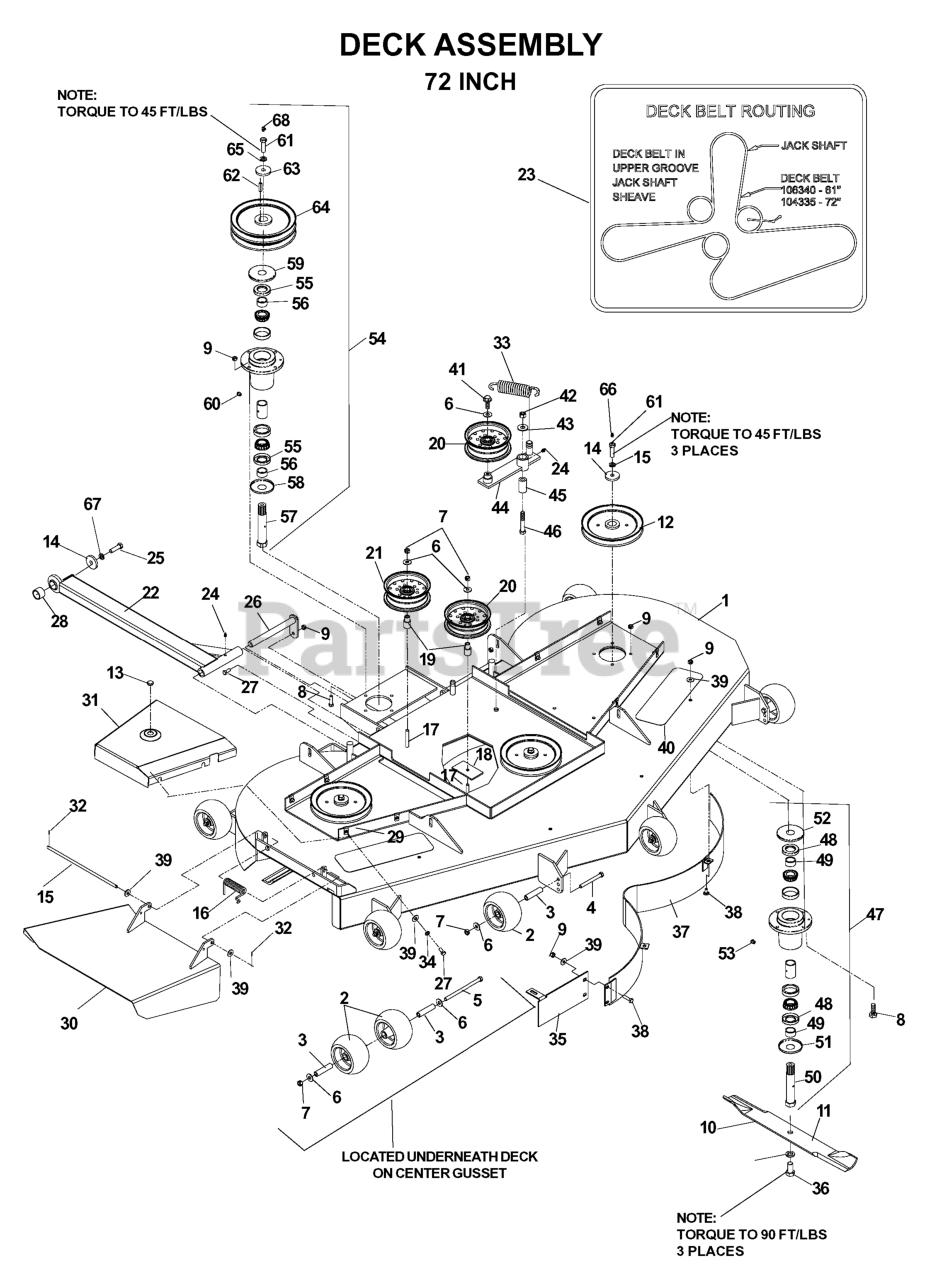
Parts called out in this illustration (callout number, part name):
1	DECK W/DECALS 72" HUS
2	ANTI-SCALP ROLLER
4	HCS 3/8C X 3 1/2
5	BOLT 3/8 X 6" GRD 8
6	WASHER 3/8 FLAT
7	NUT 3/8C CENTERBLOCK
8	HCS 5/16C X 1
9	NUT 5/16C CENTERLOCK
10	BLADE OEM - 25"
11	BELLEVILLE SPRING WASHER
12	RP PULLEY - 72"
13	PLUG, BUTTON HOLE
14	SPINDLE WASHER
15	PIN 5/16 X 11-1/2 PIVOT SPEC
16	SPRING, TORTION
17	HCS 3/8C X 2 1/2
18	SUPPORT PLATE
19	IDLER BUSHING
20	IDLER PULLEY
21	IDLER PULLEY (TALL)
22	STRUT WELDMT - R.H
23	BELT, DECK
24	ZERK
25	HCS 7/16F X 1 1/2
26	PIN WELDMENT
27	HCS 5/16C X 3/4
28	SPACER, STRUT
29	U-CLIP 5/16-18 NUT RETAINER
30	DISCHARGE CHUTE
31	RT 72 SHIELD CE ORANGE
32	COTTER PIN
33	DECK SPRING
34	WASHER.LOCK.HVY.HLCL.SPR.5/16
35	BAFFLE/CENTER-FLAT BLK
36	HEX SCREW-5/8F X 2 GR8
37	BAFFLE/CENTER-CURVED
38	CARRIAGE BOLT 5/16C X 5/8"
39	WASHER 5/16 FLAT
40	ANTI-SKID PAD
41	4CS 3/8C X 1 SERRATED HEAD
42	NUT 1/2-13 HEX NYLOC ZD
43	WASHER 1/2 FLAT
45	PIVOT BUSHING
46	HCS 1/2C X 3 1/4
47	SPINDLE ASSY - 72"
48	SHAFT SEAL
50	SPLINED SHAFT - 72"
51	BOTTOM DUST CAP
52	TOP DUST CAP
53	PLUG-VENTED
54	JACKSHAFT ASSY LOWER
55	SHAFT SEAL
57	JACKSHAFT SPINDLE
58	BOTTOM DUST CAP
59	TOP DUST CAP
60	PLUG-VENTED
61	HCS 7/16C X 1 1/2
62	KEY 1/4 SQ X 1 1/8
63	SPINDLE WASHER
64	SHEAVE WSL
65	WASHER 7/16 LOCK
66	ZERK
67	WASHER 7/16 LOCK
